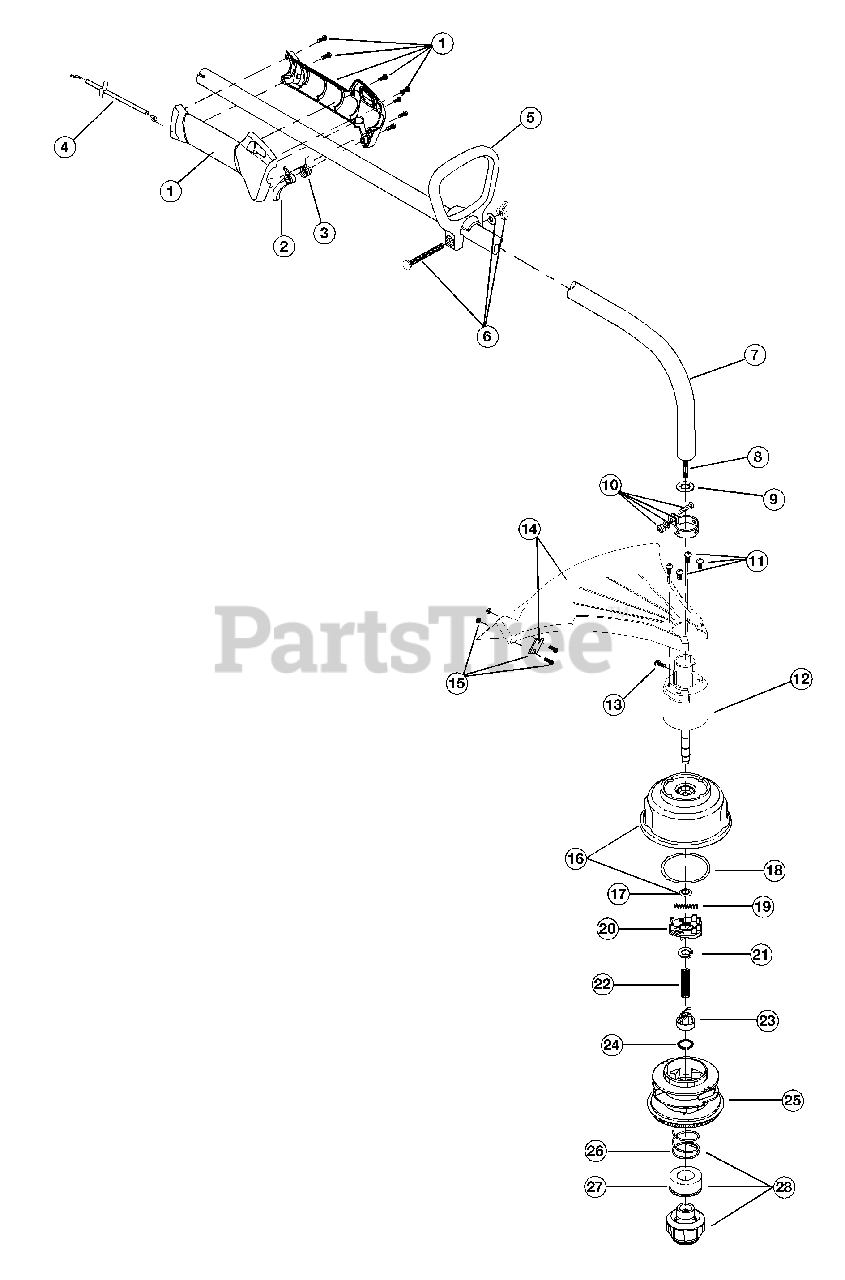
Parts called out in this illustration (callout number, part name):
1	Throttle Housing and Trigger Assembly
2	Throttle Trigger Spring
3	Throttle Trigger
4	Throttle Cable Assembly
5	D-Handle Assembly
6	D-Handle Hardware
7	Drive Shaft Housing Assembly
8	Flexible Drive Shaft
9	Palnut
10	Lower Clamp Assembly
11	Shield Mounting Screw
12	Bushing Housing Assembly
13	Anti-Rotation Screw
14	Shield and Blade Assembly
15	Blade Assembly
16	Outer Spool and Eyelet Assembly w/ Retainer
17	Retainer
18	Thrust Washer
19	Small Spring
20	Slider
23	Plunger
25	Inner Reel
26	Large Spring
27	Foam Seal
28	Bump Head Knob Assembly with Spring and Foam Seal
